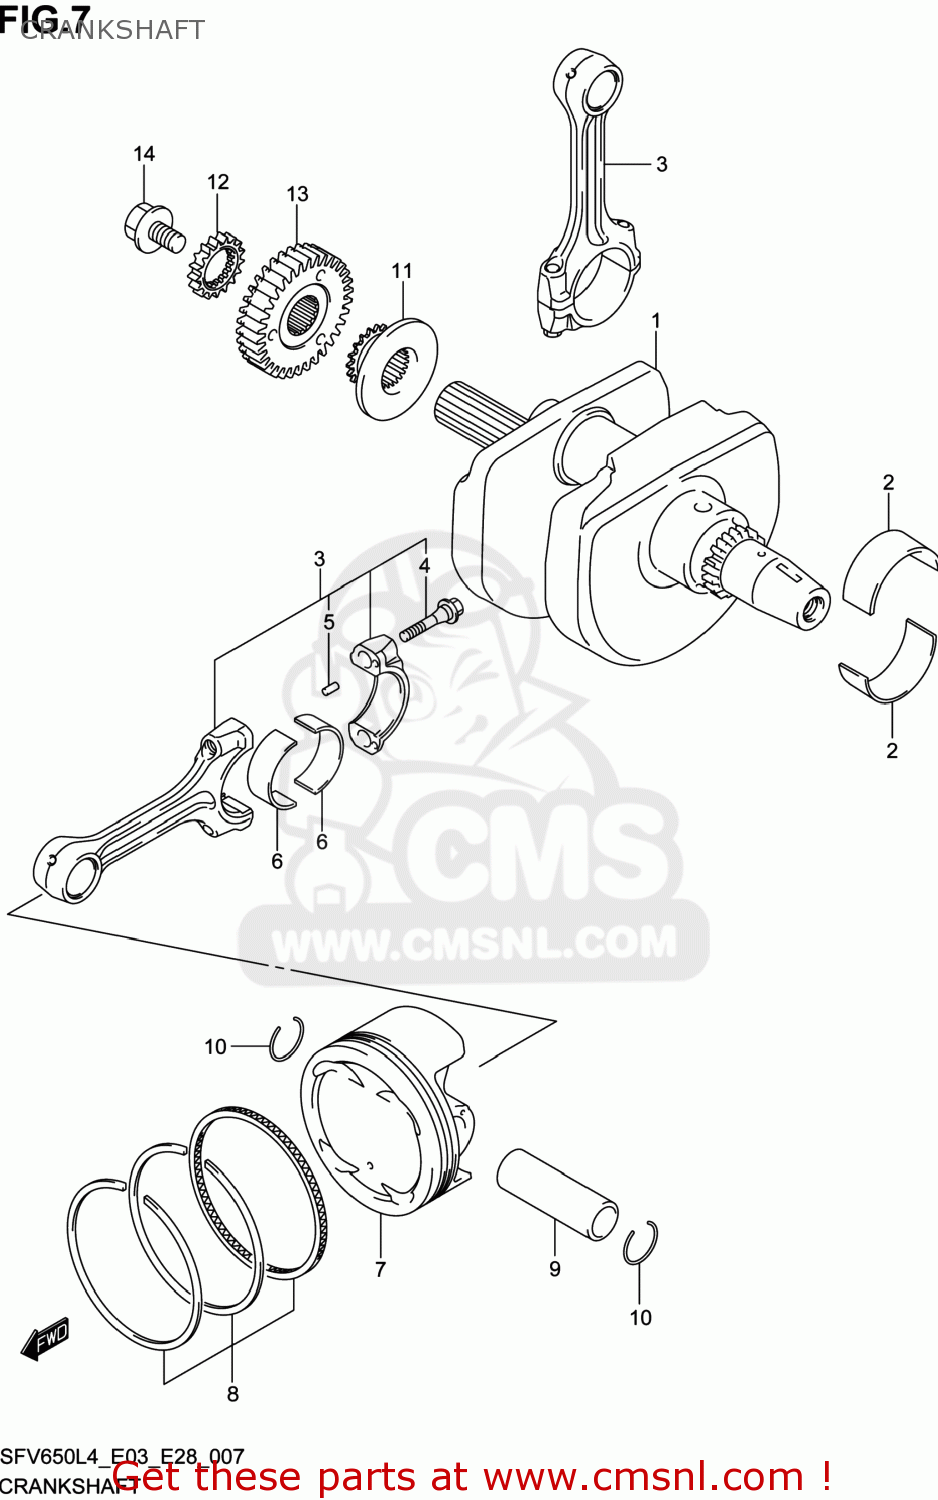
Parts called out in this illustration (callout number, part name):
1	CRANKSHAFT
2	BEARING,CRANKSHAFT
3	CONNECTING ROD ASSY
4	BOLT,CONNECTING ROD
5	PIN
6	BEARING,CRANK PIN
7	PISTON
8	RING SET,PISTON
9	PIN,PISTON
10	CIRCLIP,PISTON PIN
11	SPROCKET,CAM CHAIN DRIVE
12	GEAR,WATER PUMP DRIVE
13	GEAR ASSY,PRIMARY DRIVE
14	BOLT(10X19)
